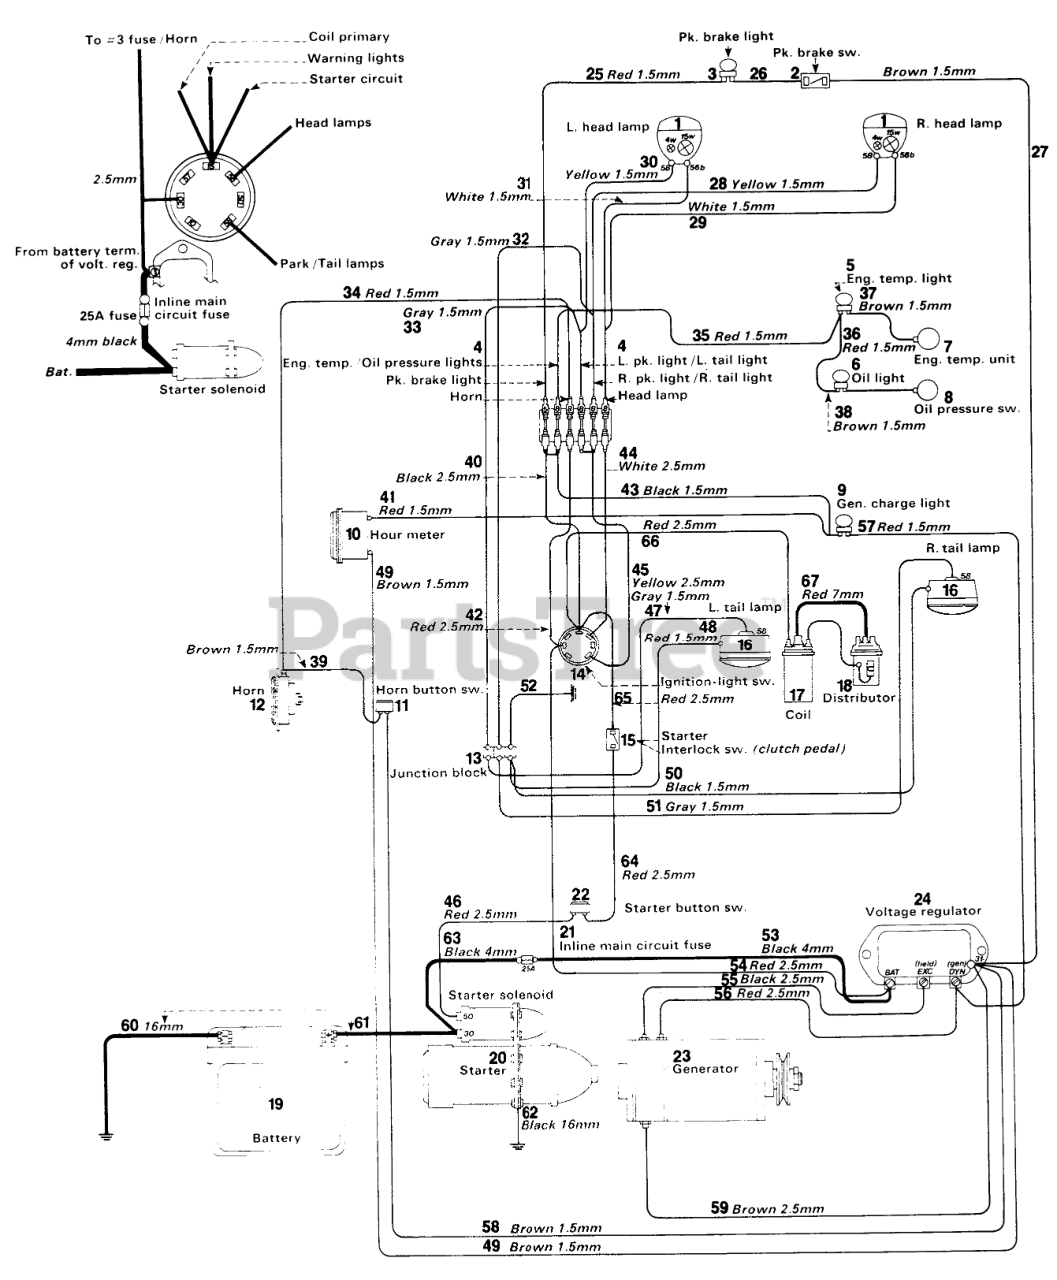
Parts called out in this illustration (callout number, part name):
1	Head-Light
2	STOP LIGHT SWITCH
3	Park Brake Light
4	Fuse Block
5	Engine Temp. Light
6	Park Brake Light
7	Engine Temp. Unit
8	Oil Pressure Switch
9	Park Brake Light
10	Hour Meter
11	Horn Button Switch
13	Junction Block
14	Ignition-Light Switch
15	STOP LIGHT SWITCH
16	Tail Lamp (Left and Right)
17	Ignition Coil
18	Distributor
20	Starter
21	Fuse 25A
22	Starter Push Button
23	Generator
24	Regulator
25	Lead Red, Fuse 5A-Ignition for Lamp
26	Lead Red, Ignition for Lamp to Indicator Lamp
27	Lead Brown, Regulator to Indicator Lamp
28	Lead Yellow, Fuse to Park Light Right
29	Lead White, Fuse to Headlight Right
30	Lead Yellow, Fuse to Park Light Left
31	Lead White, Fuse to Headlight Left
32	Lead Grey, Fuse to Distributor
33	Lead Grey, Fuse to Distributor
34	Lead Red, Fuse 8A to Horn
35	Lead Red, Fuse 8A to Indicator Lamp
36	Lead Red, Indicator Lamp for Water to Indicator Lamp for Oil
37	Lead Brown, Indicator Lamp
38	Lead Brown, Indicator Lamp for Oil-Oil Pressure Switch
39	Lead Brown, Horn Push Button to Horn
40	Lead Black, Light Ignition 15 to Fuse 5A
41	Lead Red, Hour Meter-Indicator Lamp
42	Lead Red, Fuse 8A
43	Lead Black, Fuse 8A to Indicator Lamp
44	Lead White, Light Ignition 56 to Fuse 8A
45	Lead Yellow, Light Ignition 58 to Fuse 8A
46	Lead Red, Starter 50 to Push Button
47	Lead Grey, Distributor to Taillight Left
48	Lead Red, Distributor to Junction Block
48	Insulating Hose
49	Lead Brown, Hour Meter
50	Lead Black, Distributor
50	Insulating Hose
51	Lead Grey, Distributor to Taillight Right
52	Lead Brown, Frame
53	Lead Black, Fuse to Battery
54	Lead Red, Regulator BAT to Light Ignition 30
55	Lead Black, Regulator EXC to Generator
56	Lead Red, Regulator DYN to Generator DYN
57	Lead Red, Indicator Lamp to Regulator DYN
58	Lead Brown, Horn Push Button Switch
59	Lead Brown, Generator D
60	Lead Black, Battery to Ground
61	Lead Black, Battery to Starter
62	Ground Cable Chassis-Engine
63	Lead Black, Starter Solenoid to 25 Amp Fuse
64	Lead Red, Indicator to Push Button
65	Lead Red, Light Ignition 15 to Indicator
66	Lead Red, Ignition Switch 15 to Ignition Coil
67	Ignition Cable
